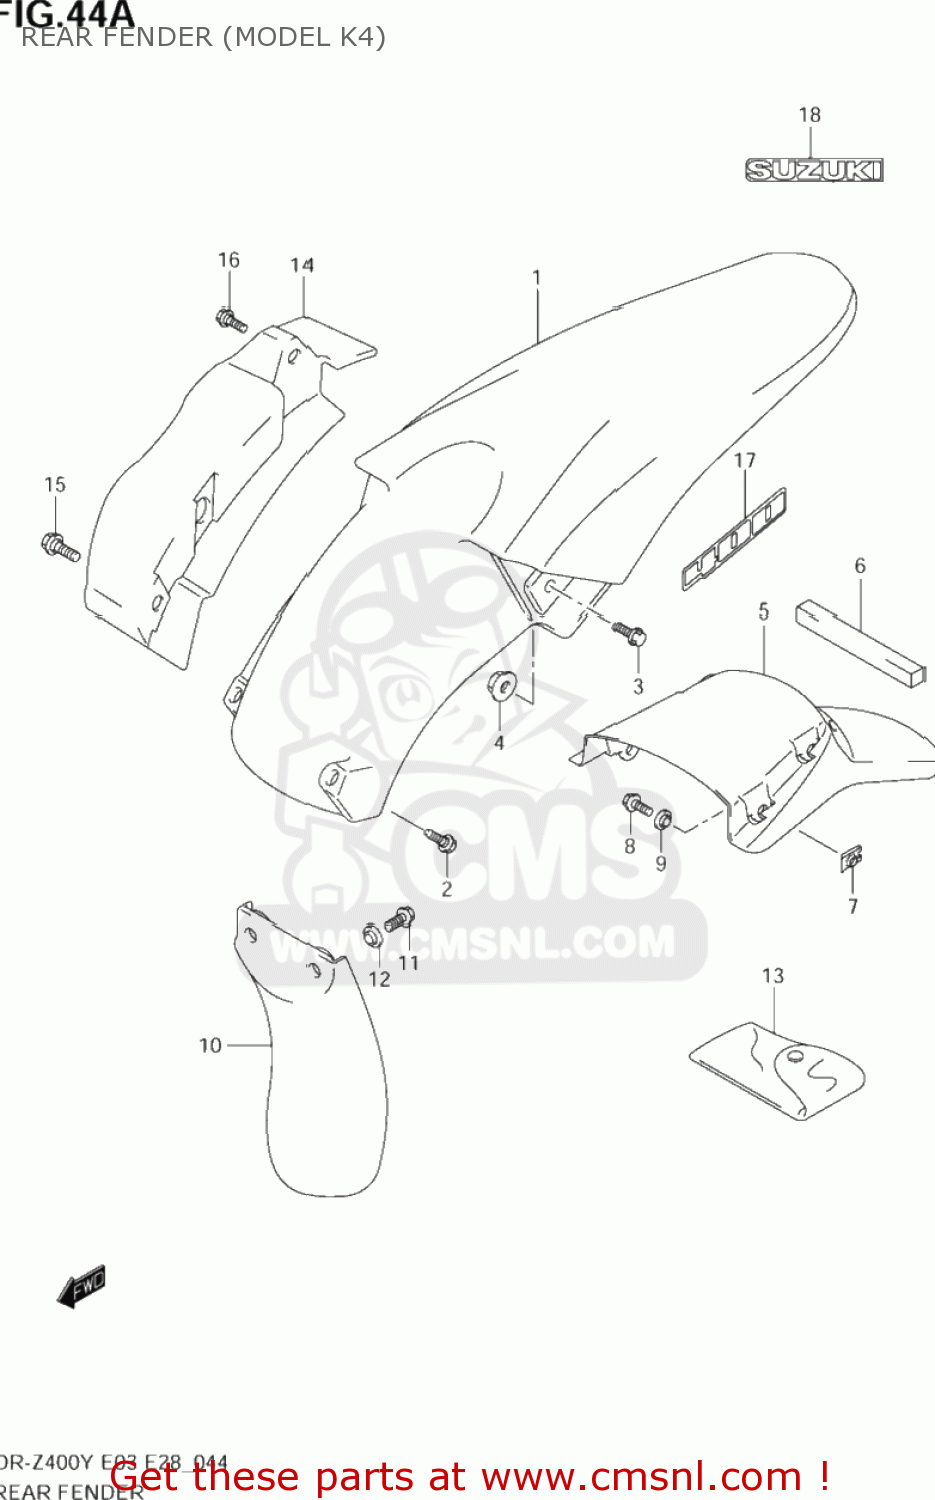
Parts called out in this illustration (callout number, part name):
1	FENDER,RR
2	BOLT(6X16)
3	BOLT(6X18)
4	NUT
5	EXTENSION,RR FENDER
6	CUSHION,RR EXTENSION
7	NUT
8	BOLT
9	WASHER (5X14X1)
10	MUDGUARD,RR FENDER FR
11	BOLT
12	WASHER
13	SPANNER,OPEN
14	MUDGUARD,RR FENDER,R
15	BOLT(6X18)
16	BOLT
17	EMBLEM,RR FENDER
18	EMBLEM,RR
